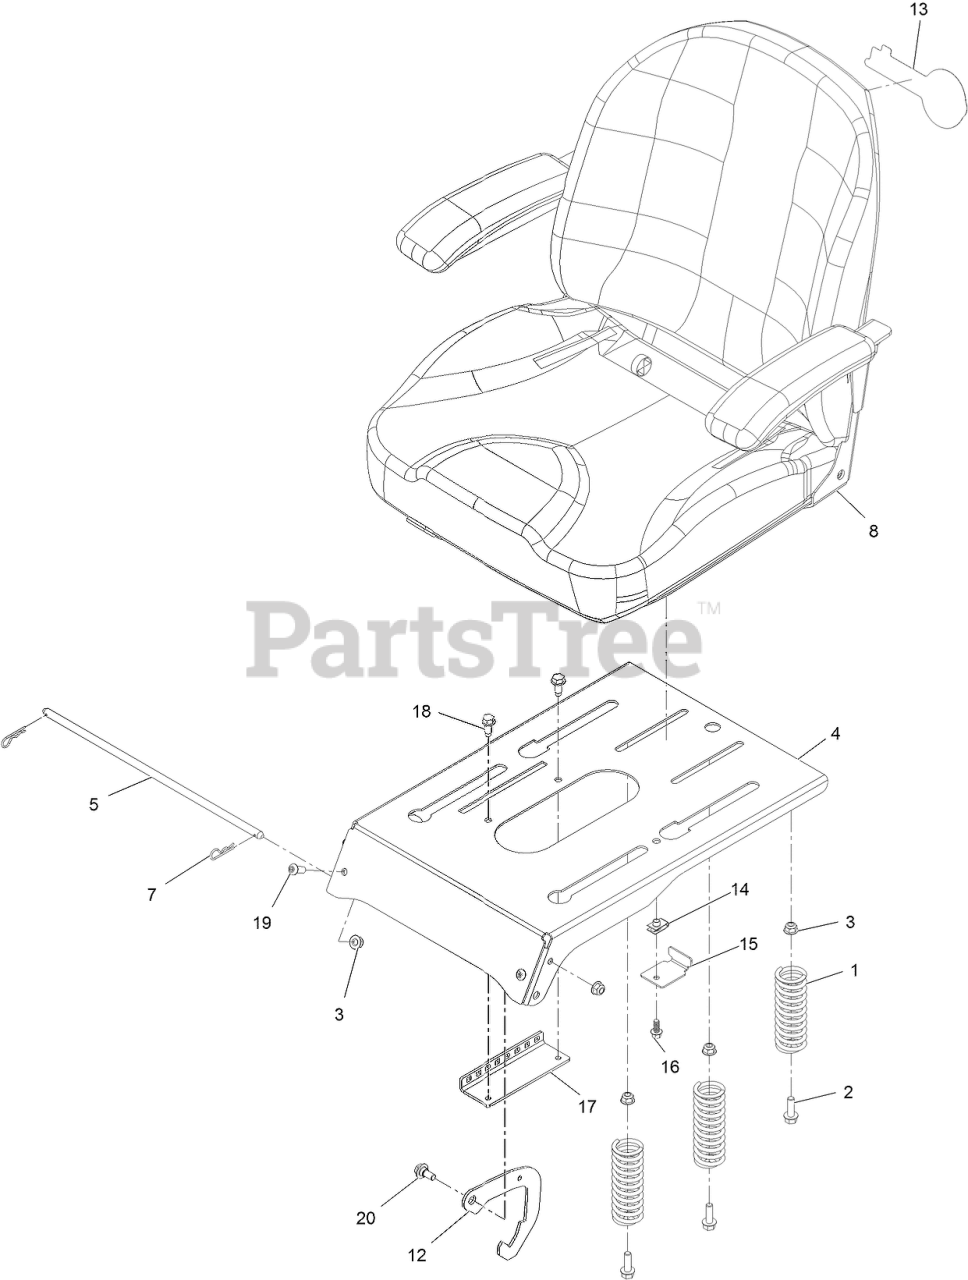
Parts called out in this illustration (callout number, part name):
1	SPRING-COMPRESSION
2	SCREW-HHF
3	NUT-HF, NI
4	PAN-SEAT, DELUXE
5	Rod-Pivot, Narrow
7	PIN-COTTER
8	SEAT ASM, EXMARK
12	Seat Latch
13	DECAL, EXMARK LOGO
15	Bracket-Stop, Seat
16	SCREW-HHF
17	BRACKET-LATCH, SEAT
18	Screw-HWH 5/16-18 X 3/4 Tf
19	SCREW-HSBH
20	SCREW-SHOULDER
